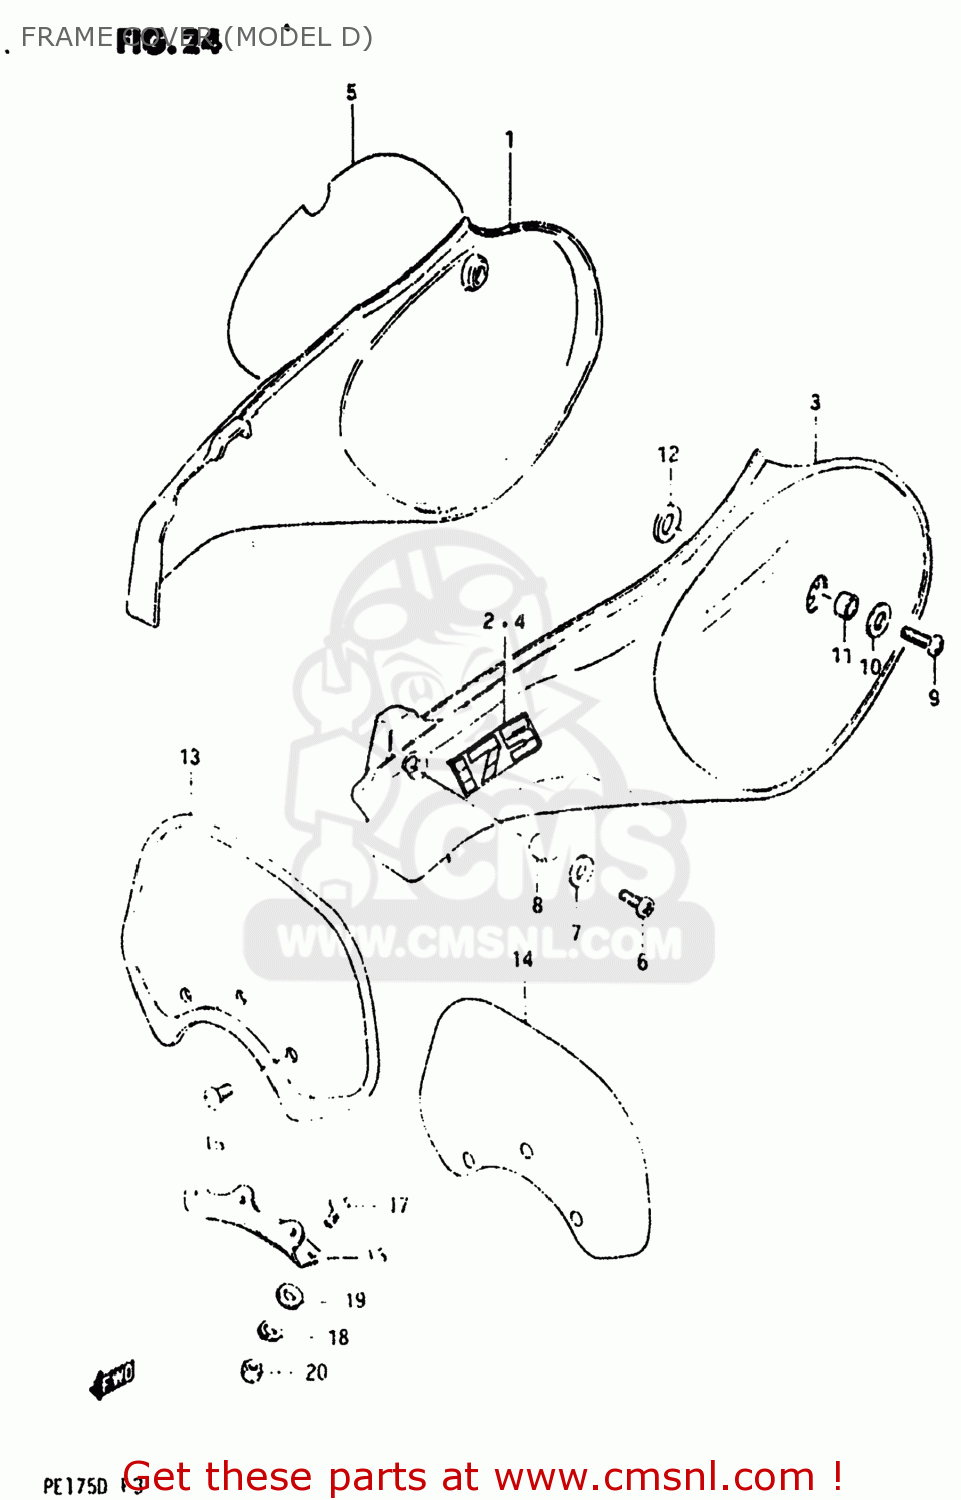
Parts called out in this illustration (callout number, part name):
1	COVER,FRAME,RIGHT
2	EMBLEM,FRAME COVER,RIGHT
3	COVER,FRAME,LEFT
4	EMBLEM,FRAME COVER,LEFT
5	EMBLEM,NBR PLATE
6	SCREW
7	WASHER
8	SPACER (6.1X8X12)
9	SCREW
10	WASHER
11	SPACER
12	GASKET
13	PLATE,FRONT NUMBER
14	EMBLEM,FRONT NUMBER PLATE
15	SCREW
16	BRACKET FR NUM PLATE
17	SCREW
18	LOCK WASHER
19	WASHER
20	NUT
